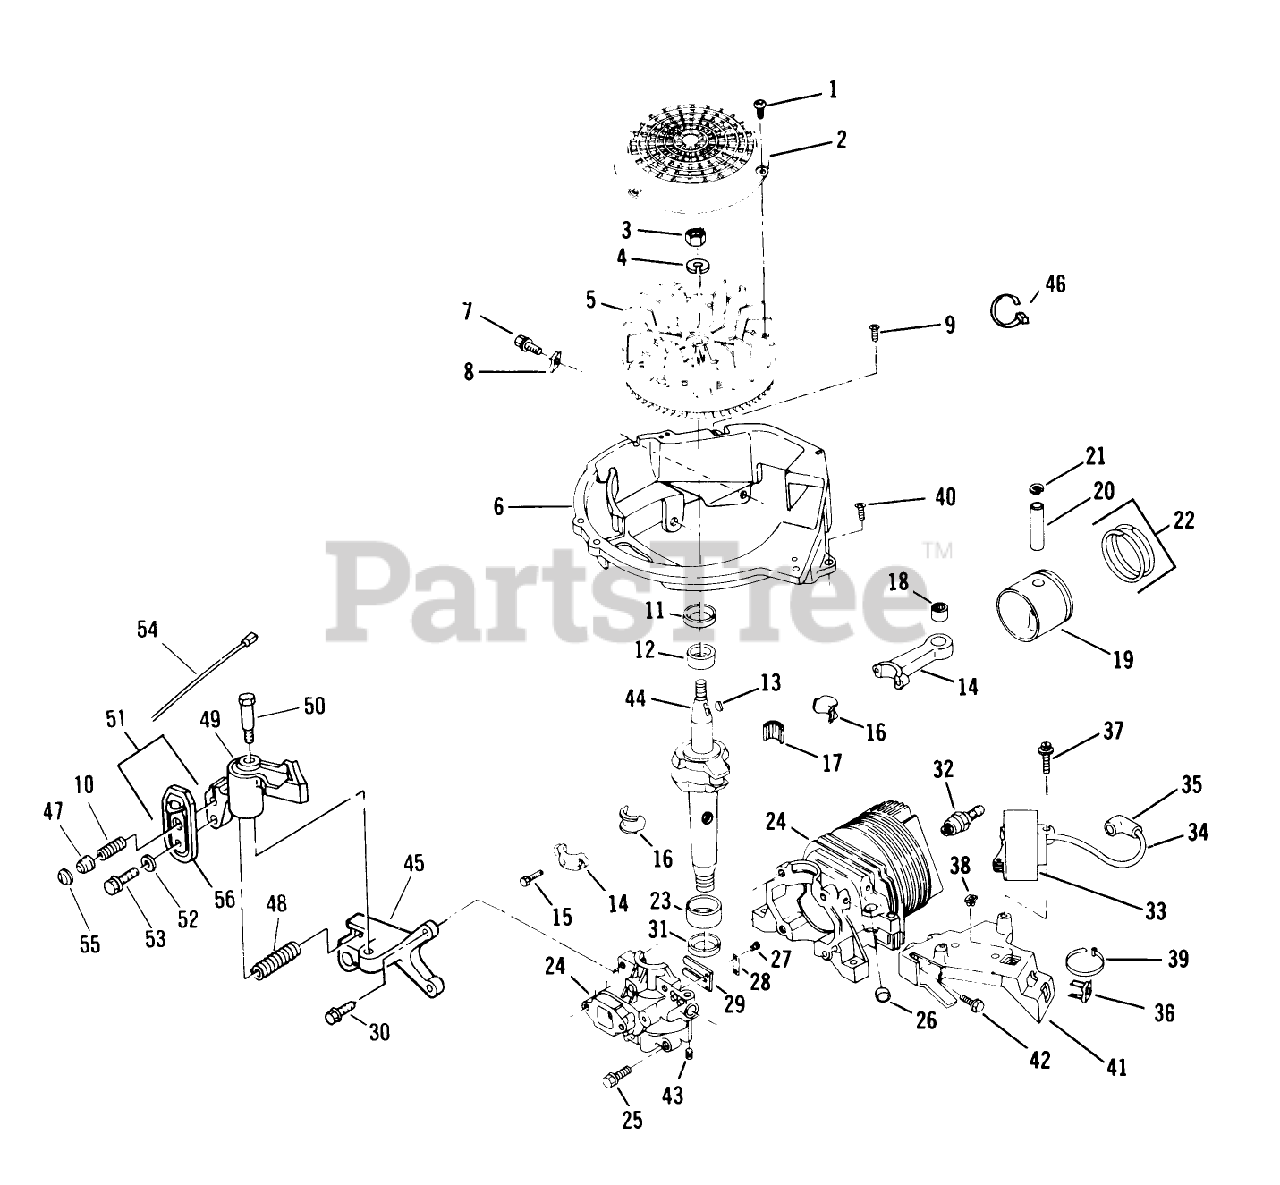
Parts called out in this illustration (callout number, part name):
1	SCREW F
2	SCREEN F'WHEEL S
3	NUT
5	FLYWHEEL ASSY F
7	SCREW-SEMS
9	SCREW F
10	SPRING
11	SEAL-OIL
12	BEARING V
13	KEY
15	SCREW-HSH
16	LINER ASM
17	BEARING-NEEDLE
18	BEARING AY F
21	RING-RETAINING
23	BEARING V
25	SCREW S
26	PLUG-CORE VF
27	SCREW-HH
28	PLATE-BACKUP, REED
31	SEAL-OIL
34	HT LEAD&COVER XEV
36	NUT-CLIP
38	NUT-CLIP
40	SCREW F
41	C.D. BRKT F
45	BRACKET-BRAKE F
47	ACTUATOR-LEVER, BRAKE
48	SPRING-BRAKE
52	WASHER
54	WIRE LEAD AY F
55	RETAINER S
